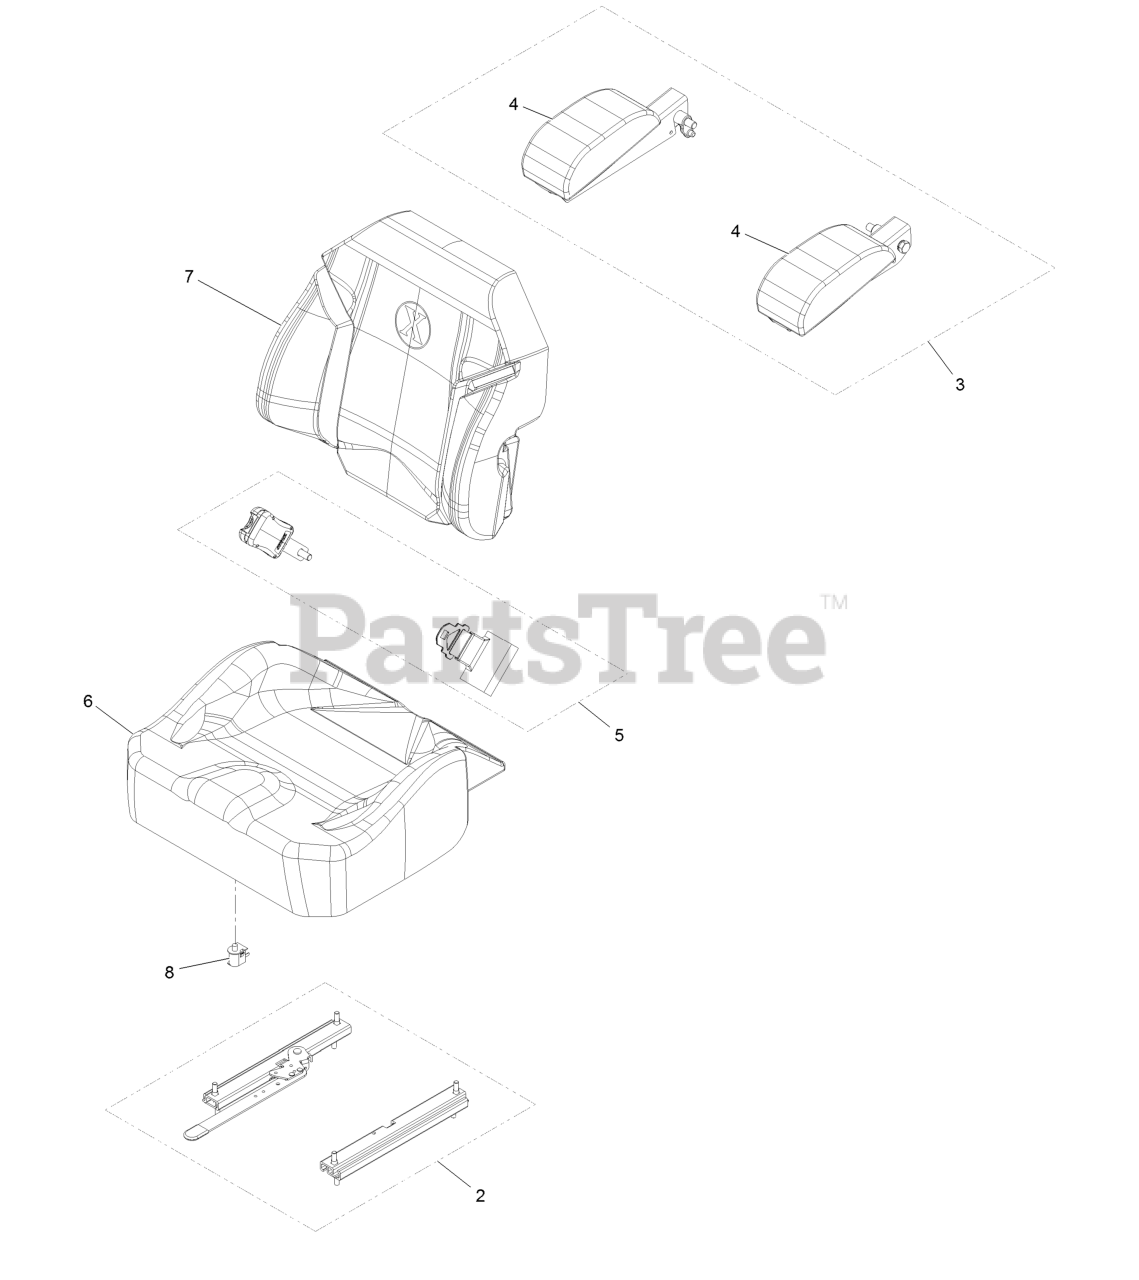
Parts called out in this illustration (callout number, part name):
2	SEAT TRACK SET
3	KIT-ARM REST SET
4	KIT-ARM REST PADS
5	SEAT BELT KIT
6	SEAT CUSHION COVER
7	SEAT BACK COVER
8	SWITCH-BAIL
